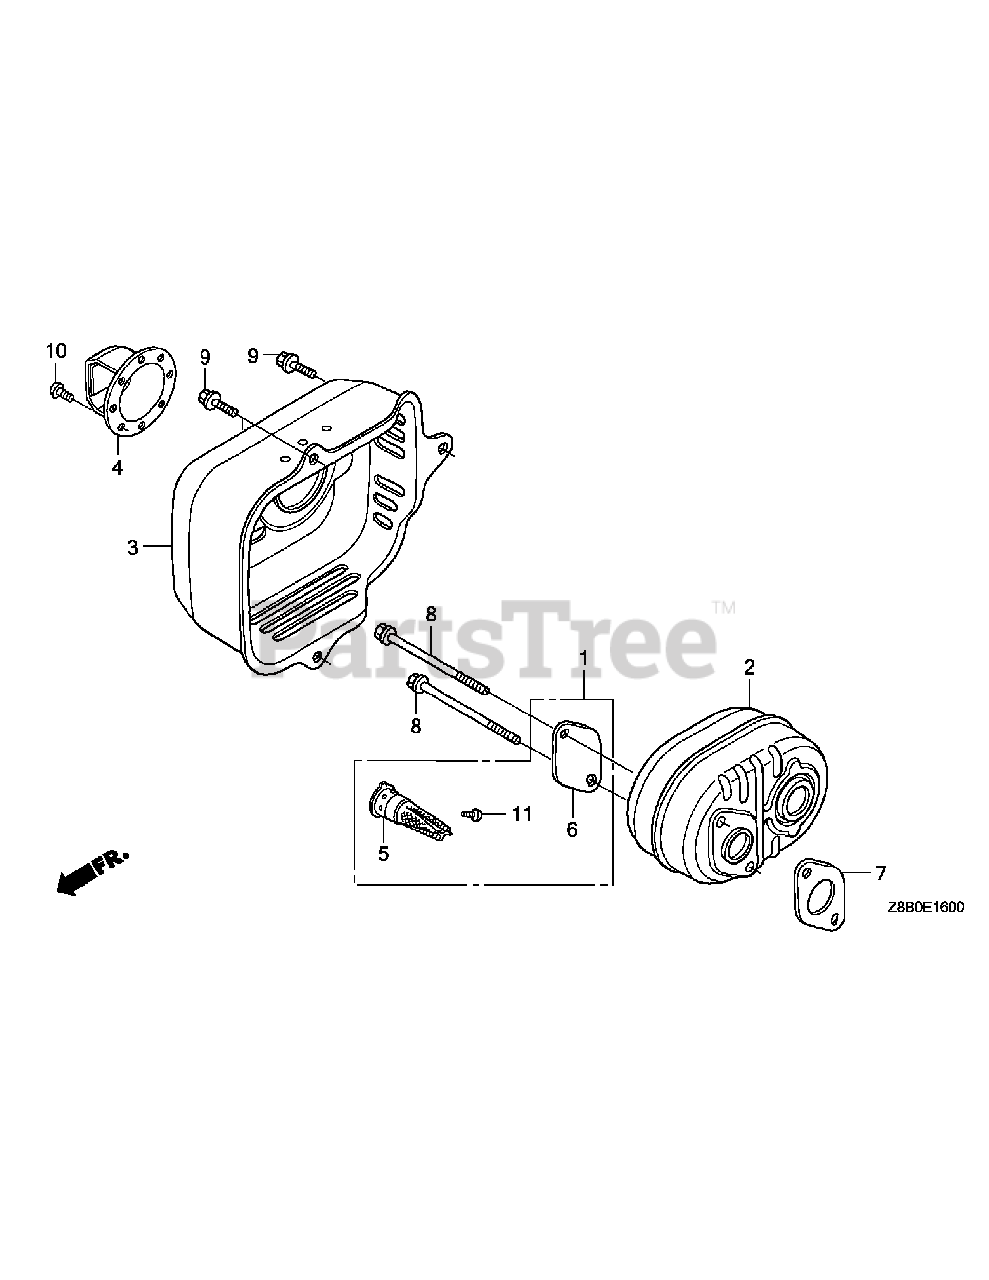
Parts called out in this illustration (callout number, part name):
1	ARRESTER KIT, SPARK
2	MUFFLER COMP.
3	PROTECTOR, MUFFLER
4	CAP, MUFFLER
5	ARRESTER COMP., SPARK
6	PLATE, ARRESTER NUMBER
7	GASKET, MUFFLER
8	BOLT, FLANGE, 6X79(CT200)
9	BOLT, FLANGE, 6X12(CT200)
10	SCREW, TAPPING, 4X6
11	SCREW, TAPPING, 4X6
